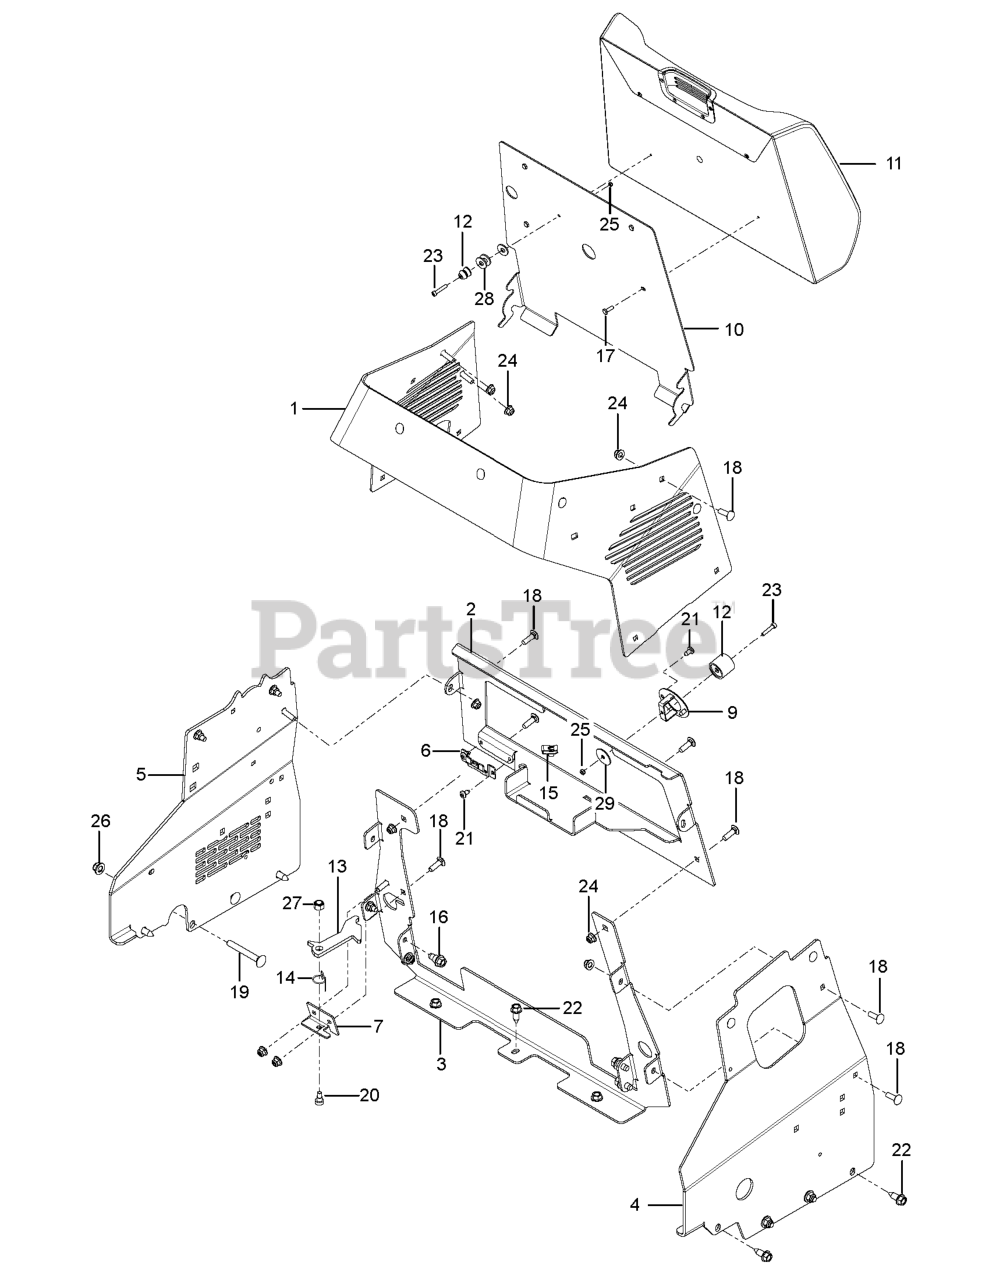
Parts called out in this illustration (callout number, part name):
1	COLUMN FRONT STAND-ON MS668 OR
2	COLUMN REAR LOWER VZ MS498 GRE
3	COLUMN REAR TOP VZ MS498 GREY
4	COLUMN SIDE LH VZ MS668 ORANGE
5	COLUMN SIDE RH VZ MS668 ORANGE
6	BRACKET FUSE RELAY HOUSING ST
7	BRACKET PLATFORM HOLDBACK MS 4
9	HOLDER HOLDBACK CRADLE
10	DOOR COLUMN REAR VZ MS498 GREY
11	PAD OPERATOR CUSHION HUSQVARNA
12	HOLDER.ASM.STEM.BASE.WASHER
13	LATCH PLATFORM HOLDBACK MS428
14	SPRING PLATFORM HOLDBACK
15	U-CLIP 5/16-18 NUT RETAINER
16	BOLT.SHOULDER
18	RHSSNB 5/16C X 1.0
19	3/8-16 X 3` CARR BOLT
20	SB 3/8-16 X 3/8 SKT HD ZD
21	SCREW T-30 1/4-20 X
22	SCREW 3/8-16X1
23	SCREW.HEXAGON.HD.M5X25.8.8.ZPB
24	5/16-18 NYLOC FLANGE NUT
25	NUT.LOCK.M5.8.ZP-Y
26	NUT 3/8-16 HEX FLG NYLOC ZD
27	NUT 3/8-16 NYLOC
28	WASHER.ROUND.5X20X1.5.ZPB
29	WASHER FENDER 1/4"X1.25"X0.08"
